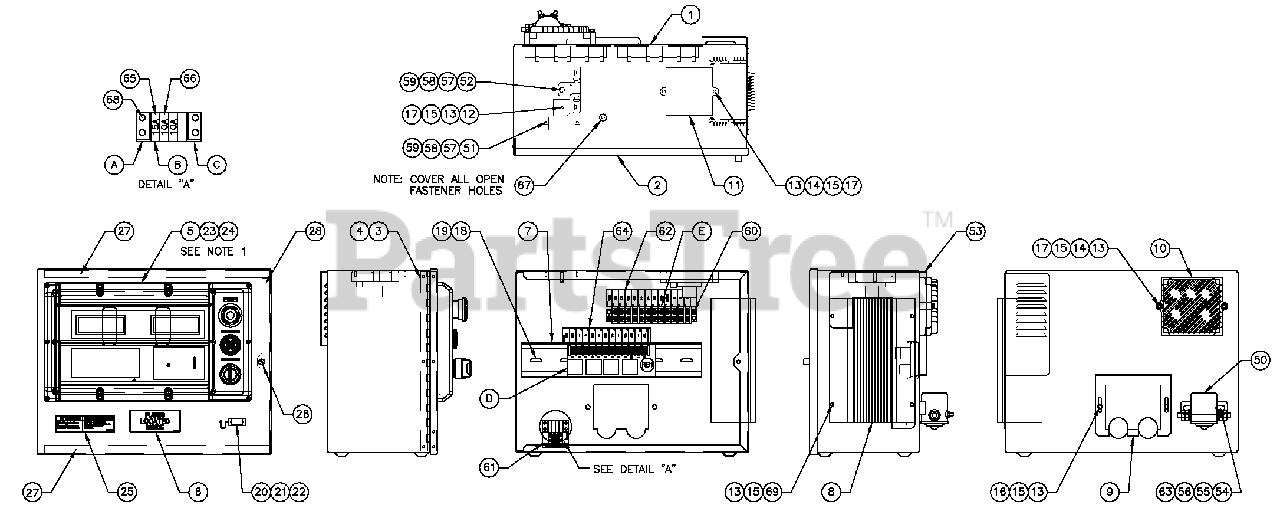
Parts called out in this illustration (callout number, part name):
1	ENCLH/G CONTROL PANEL
2	COVER CONTROL PANEL
3	HINGECONTINUOUSH PANEL
4	RIVET POP .125X .275SS
5	ASSYPROGRAMMEDH-100
6	DECAL FUSES LOCATED INSIDE
7	RAILSNAPTRACK PCB HOLDER BULK (12"LG)
8	ASSY PCB 10A UL BATT CHRGR12V
9	PLATE HARNESS CLAMP
10	ASSY PCB PWR AVR W/AMP HEADER
11	ASSY PCB BOSCH GOV DRIVER
12	DIO BRIDGE25A 600V
13	WASHER LOCK M5
14	SCREW PPHM M5-0.8X 30SS
15	WASHER FLAT M5
16	SCREW HHPM M5-0.8 X 12
17	NUT HEXM5-0.8 G8 YEL CHR
18	WASHER FLAT M4
19	SCREW PHTT M4-0.7X 10ZYC
20	CONN DUST CAP W/CHAIN DB9
21	WASHER FLAT M3.5
22	SCREW PHTT M3.5-0.6 X 10
23	SCREW PPHM M4-0.7X 8 BLXOX
24	WASHER LOCK #8-M4
25	DECAL WRN BATT CHRG12/24V BI
26	M5-0.8 CAPTIVE PANEL KNLD HD
27	SEAL COVER 3.18 X 12.7X 382
28	SEAL COVER 3.18 X 12.7X 283
29	HARNESS H-PNL INTEGRATED SW (NOT SHOW
50	RELAY CONTACTOR 12VDC
53	COVER CONTROL PANEL SIDE
54	SCREW HHC 1/4-20X 3/4G5
55	WASHER FLAT M6-1/4
56	WASHER LOCK M6-1/4
57	WASHER LOCK M3
58	NUT HEXM3-0.5 G8 YEL CHR
59	WASHER FLAT M3
60	SCREW PHTT#6-32X 5/8ZYC
61	DECAL CPL CONTROL PANEL FUSES
62	DECAL CPL 5.4/6.8LTB3
63	NUT HEX 1/4-20 STEEL
64	DECAL CPL 5.4/6.8L RELAY BOARD
65	FUSE ATO TYPE 15 AMP (BLUE)
66	FUSE ATO TYPE 10 AMP (RED)
67	SEAL WEATHER.45"DIA
68	SCREW PHTT#6-32X 3/8ZYC
69	SCREW PHTT M5-0.8X 16ZYC
A	ADPTR RH SIDE WICKMANN 178.6191
B	HOLDERFUSE WICKMANN 178.6150
C	ADPTR LH SIDEWICKMANN 178.6192
D	ASSY PCB G-PANEL RELAY 12VDC
E	BLOCK TERM 20A 12X 6 X1100V
